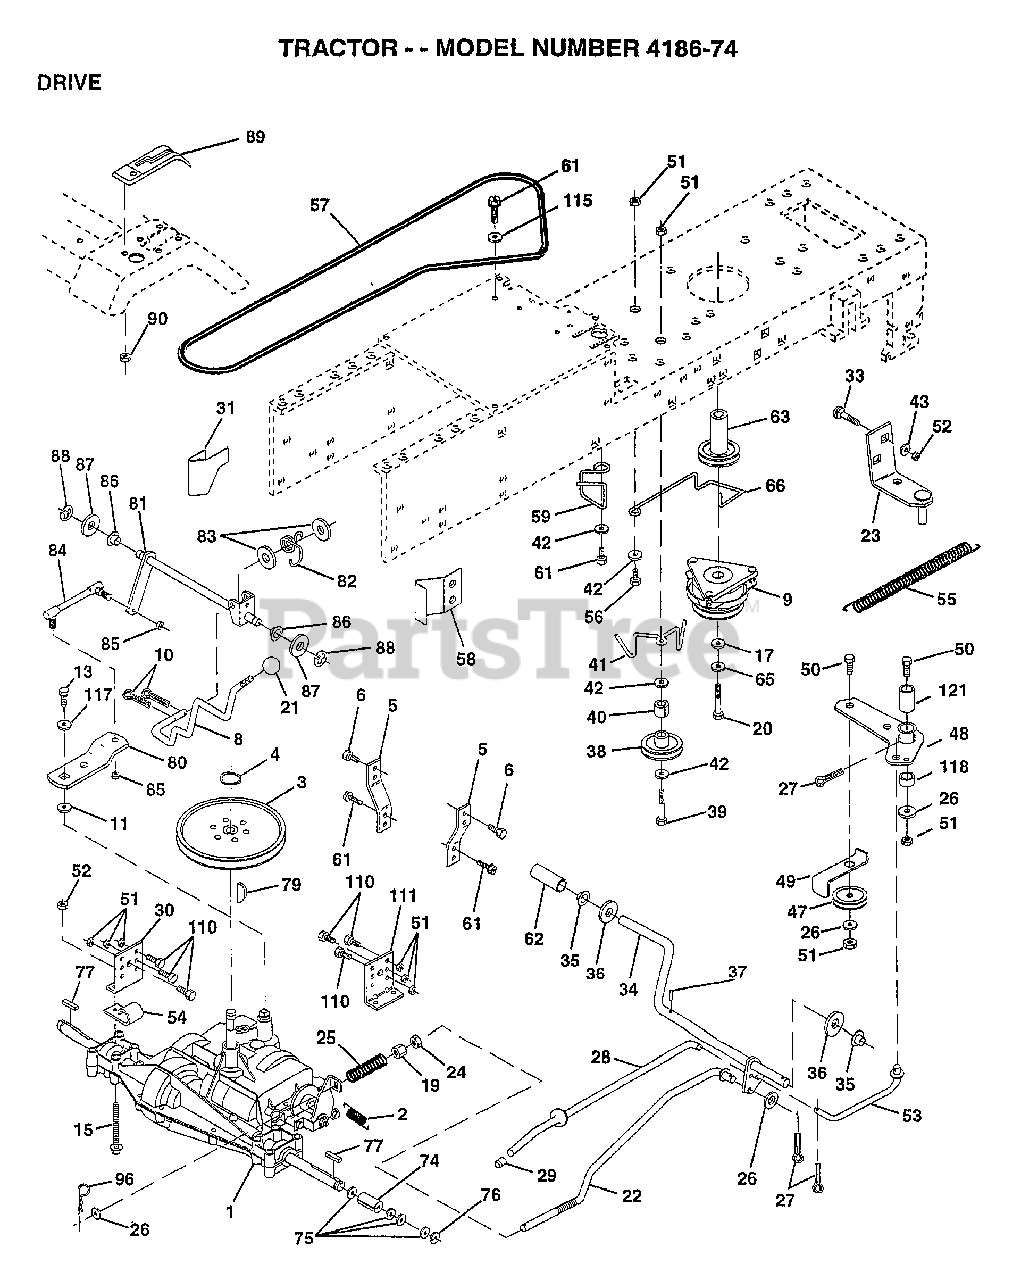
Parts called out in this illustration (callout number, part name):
3	PULLEY TRANSAXLE
4	RING
5	STRAP TORQUE
6	SCREW
8	ROD SHIFT FEND YT
10	PIN COTTER 1/8
11	WASH-SHFT PLT LT
13	BOLT.1/4-28.W/PAT
15	BOLT.HX.FLG.5/16
17	WASHER
19	NUT
20	BOLT.7/16-20X4.25
21	KNOB T (1/2-HOLE)
22	ROD.ASM.BK.44.MWR
23	BRACKET.ASM.MTG
24	NUT
25	"SPRING,ROD BRAKE"
26	WASHER
27	COTTER PIN
28	ROD.BRAKE.PARK.LT
29	PLUNGER CAP T
30	BRKT TRANS LH
31	KEEPER BELT LH
33	BOLT
34	SHAFT ASM-PEDAL F
35	NYLON BEARING
36	WASHER LT
38	PULLEY.IDLER.FLAT
39	BOLT
40	SPACER T
42	WASHER
43	WASHER T
48	BELLCRANK ASM
49	RETAIN BELT
53	"LINK, CLUTCH T"
54	"CLIP,INSULATOR"
55	"SPRING, RETURN LT"
57	BELT.GRDRV.94.75
58	"KEEPER,BELT RH"
59	KEEPER BELT CNTSP
61	SCREW
62	PEDAL COVER T
63	PULLEY ENGINE
65	LOCKWASHER
66	KEEPER-BELT
74	SPACER HYT
75	WASHER
76	E RING HYT
77	SQ KEY STD
80	"ARM,SHIFT"
81	"SHAFT,SHIFTER"
82	"SPRING,TORSION"
83	WASHER
84	"ROD LINK,SHIFT AD"
85	NUT.CNT.LOCK.1/4
86	BUSHING
87	WASHER D
88	KLIP RING
89	CONSOLE SHIFTER
90	NUT
96	RETAINER M
111	BRKT TRANS RH
115	WASHER GT
117	WASHER PM
118	SPACER-BELLCRANK
121	NYLINER-CLUTCHING
